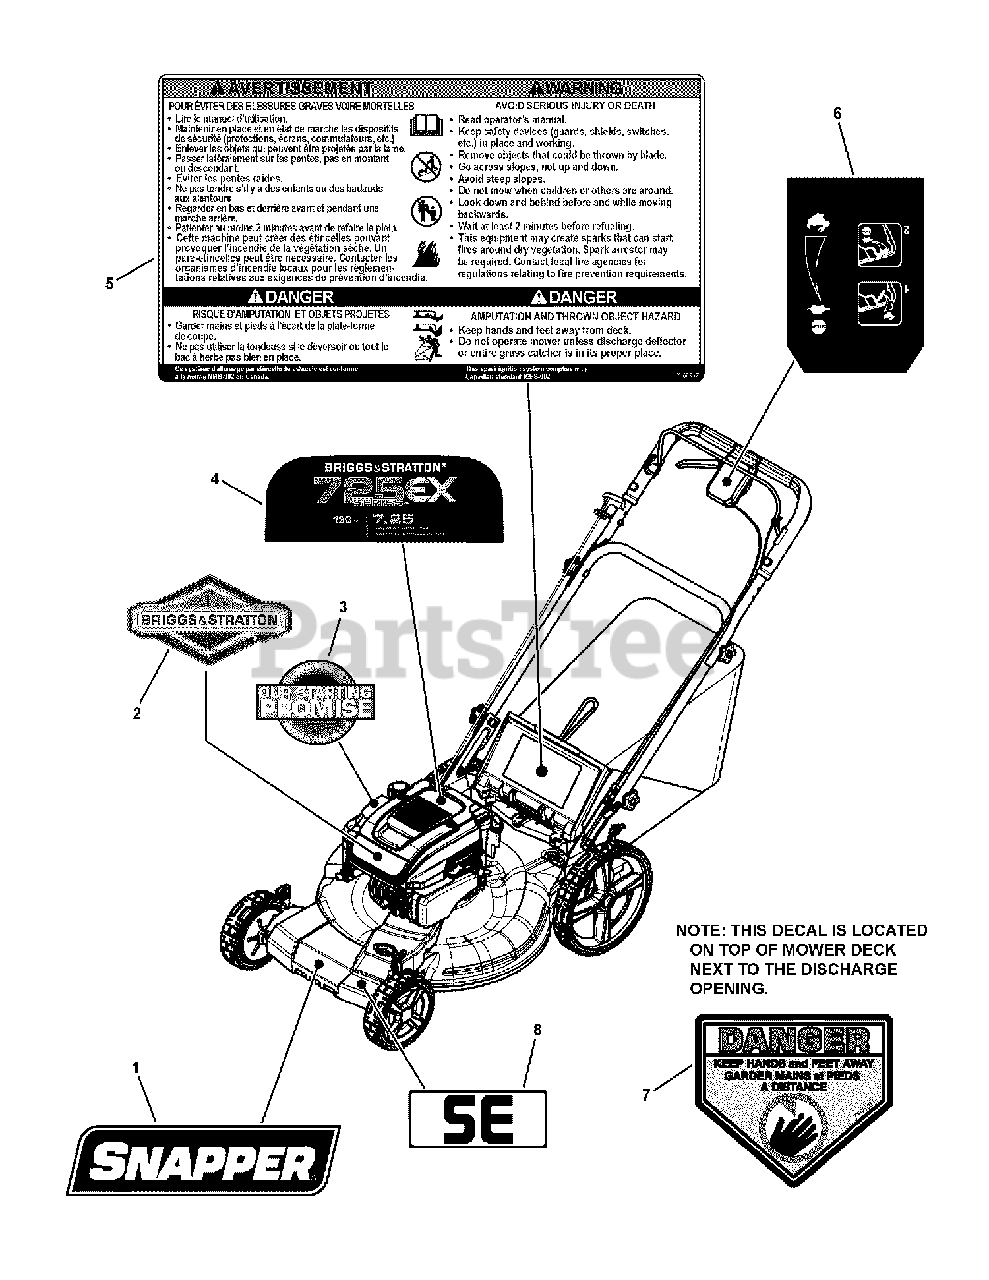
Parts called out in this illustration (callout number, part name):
1	DECAL, Front Shroud, Snapper Logo
2	LABEL, Briggs & Stratton Logo
3	LABEL, Starting Promise
4	DECAL, Engine, B&S, 725 Series
5	DECAL, Warning/Danger, WB, French/English
6	DECAL, Control, Murray vs, Euro
7	DECAL, CPSC, French/English
8	DECAL, Front Cover "SE"
